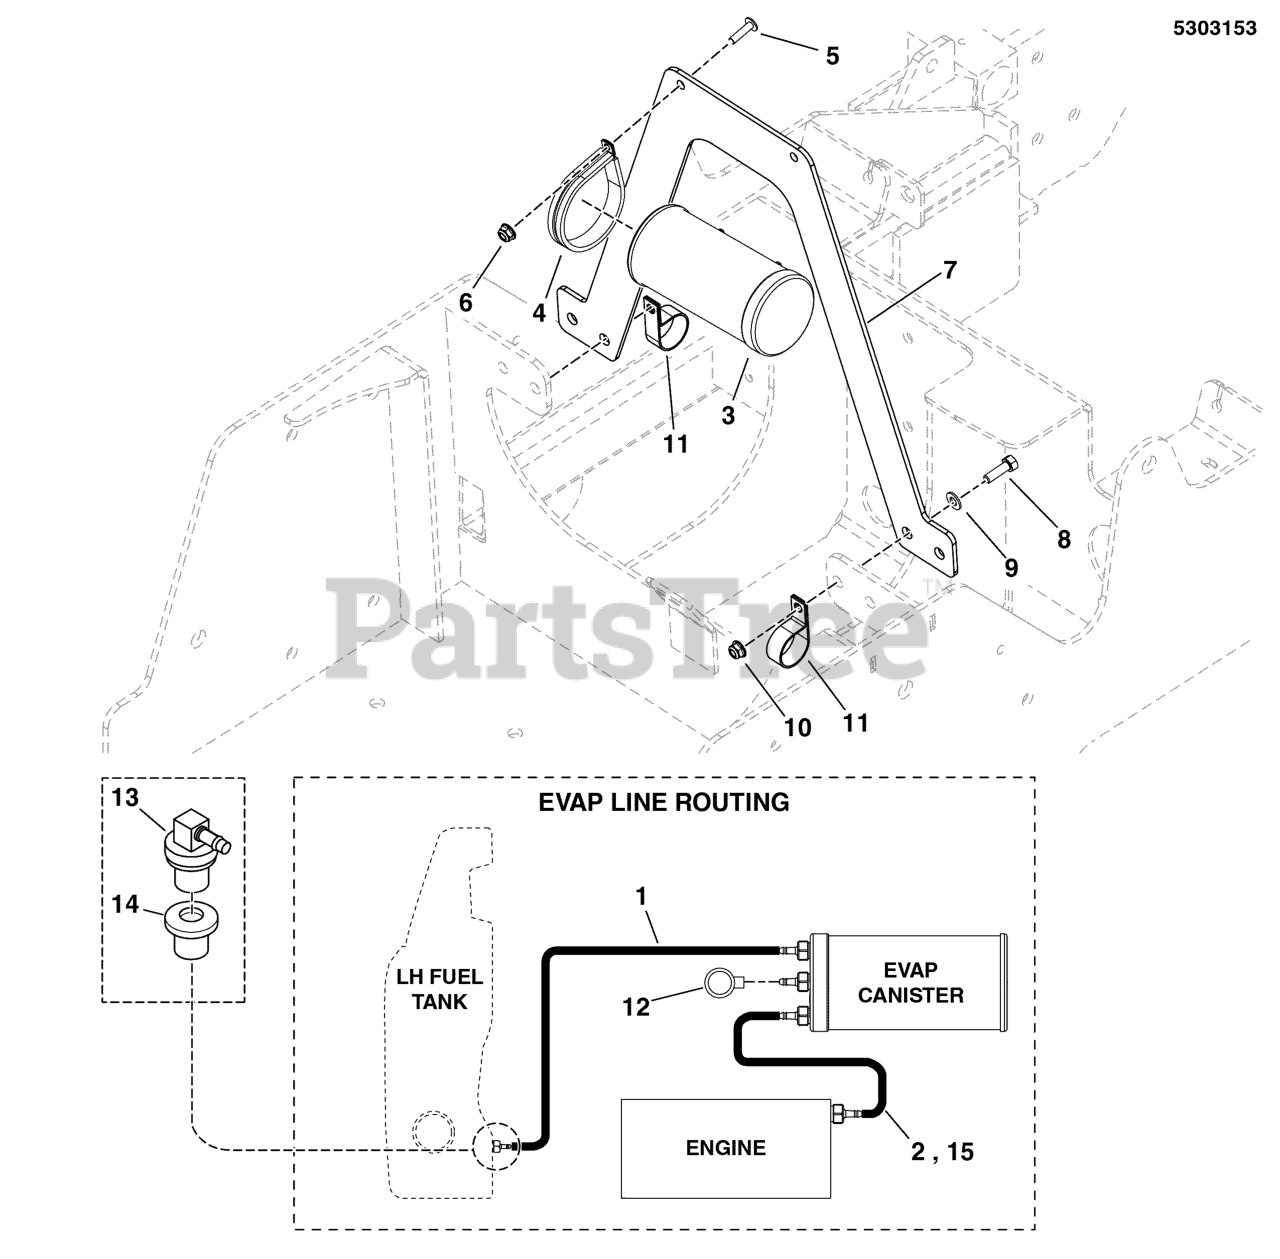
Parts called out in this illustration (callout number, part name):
1	HOSE, VAPOR, 5MM ID, 23.00 LG
2	HOSE, VAPOR, 5MM ID, 33.50 LG
3	CNSTR, CARB, 6 GAL
4	CLAMP, 3" ID, CUSHIONED, STAINLESS
6	NUT, 1/4-20 HEX NYLOCK FLANGE
7	PLATE, MOUNT, CANISTER, IS600 - BLK
8	BOLT, 5/16-18 X 1 GD5 CZ
9	WASHER, 5/16" SAE
10	NUT, 5/16-18 HEX NYLOCK FLANGE
11	CLAMP, TUBE & WIRING, 1.062 ID
12	DUST FILTER, CANISTER
13	REMOTE VENT ASSEMBLY
14	GROMMET
15	HOSE, VAPOR, 5MM ID, 31.00 LG
